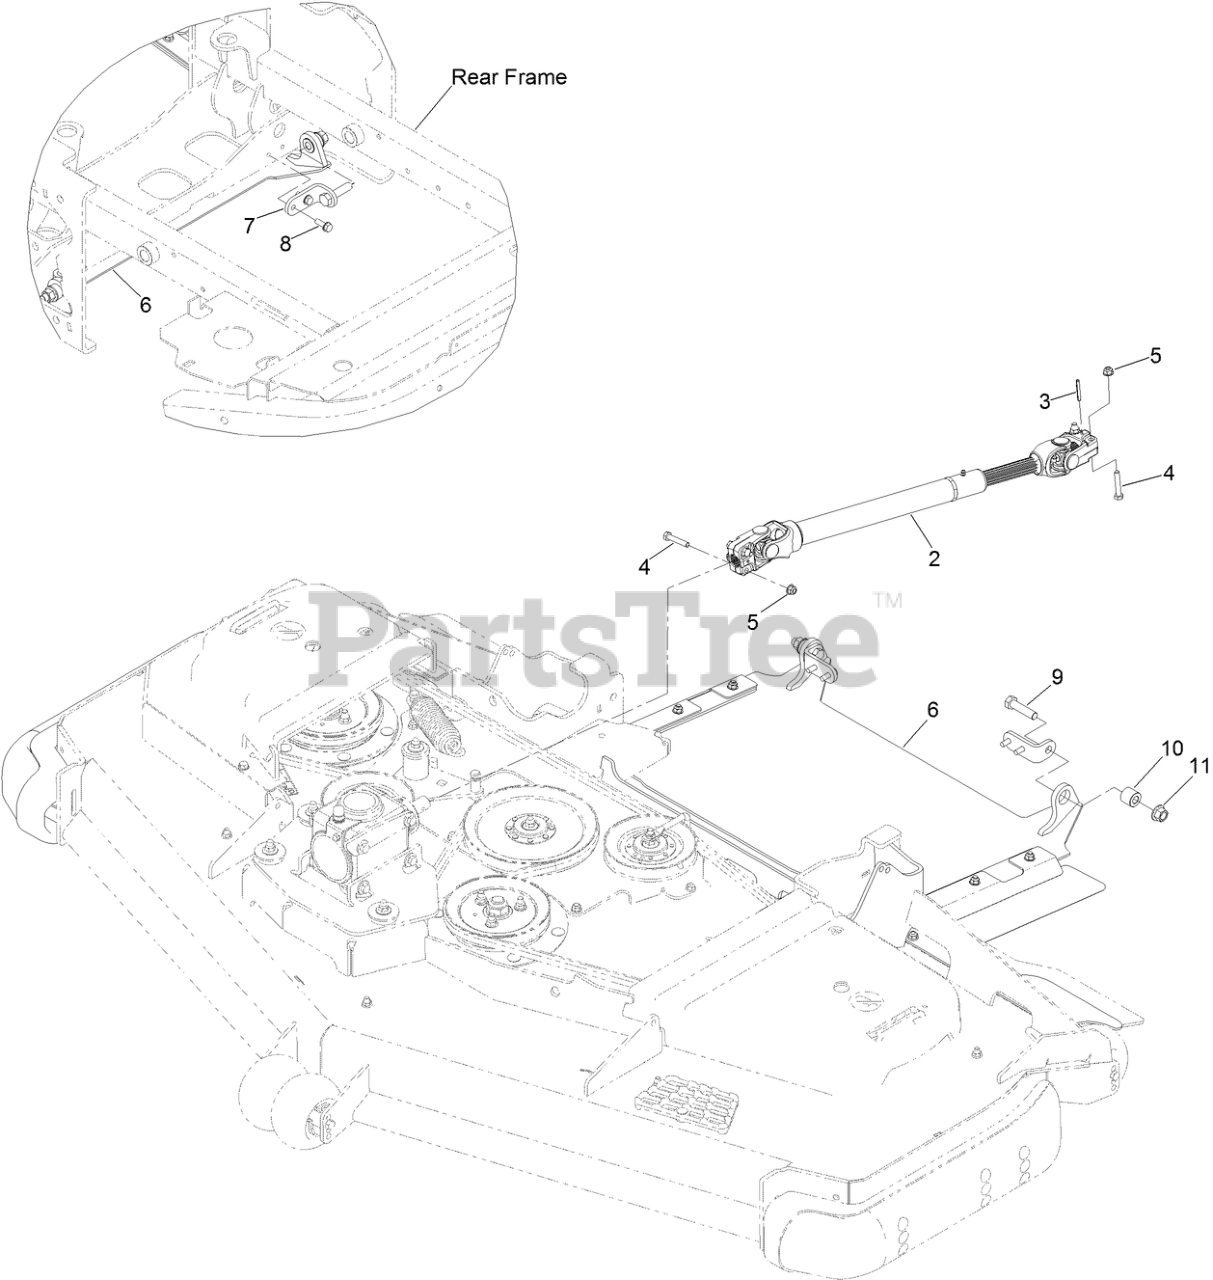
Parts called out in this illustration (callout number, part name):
2	DRIVESHAFT ASM
3	PIN-ROLL
4	SCREW-HH
5	NUT-HF, NI
6	DISCHARGE TUNNEL ASM
7	BRACKET-DISCHARGE
8	SCREW-TAPTITE
9	SCREW-HH
10	BUSHING-SLEEVE
11	NUT-LOCK
